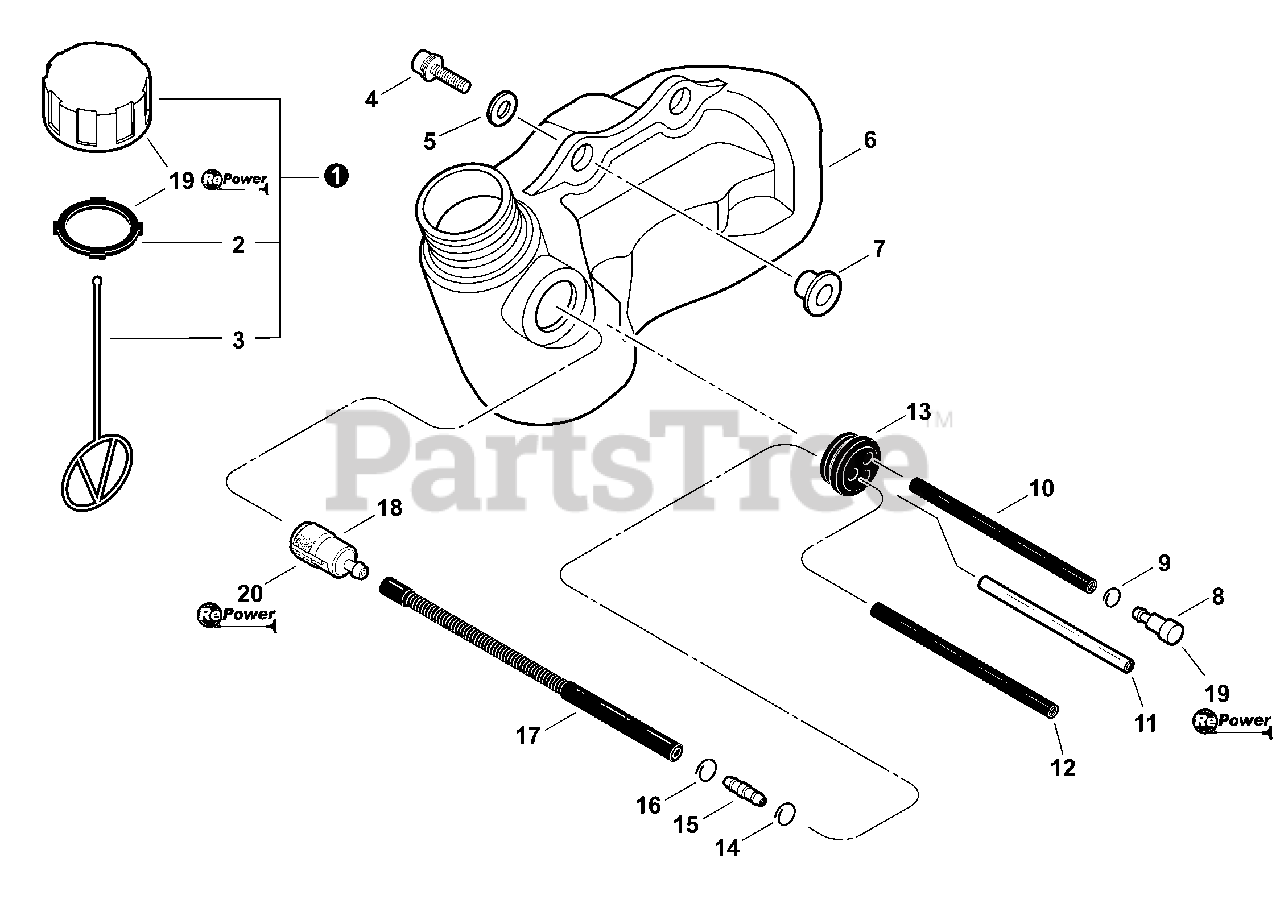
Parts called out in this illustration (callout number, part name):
1	CAP ASSY, FUEL
2	GASKET, FUEL CAP
3	CONNECTOR, CAP L= 123
4	BOLT 5×20
5	WASHER 5.5×12×0.8
6	TANK, FUEL
7	COLLAR 5
8	VENT ASSY
9	CLIP 6.6 MM
10	PIPE - 3×5×65 -- BLACK
11	PIPE, FUEL 3×6×75 CLEAR
12	PIPE, FUEL 3×6×105 BLACK
13	GROMMET, FUEL
14	CLIP 6 MM
15	CONNECTOR, PIPE
16	CLIP Ø6.5 MM
17	PIPE, FUEL 3×7×100 FLEXIBLE
18	FILTER, FUEL
19	CAP/VENT KIT - REPOWER
20	FILTER KIT - REPOWER
21	TUNE-UP KIT - REPOWER
